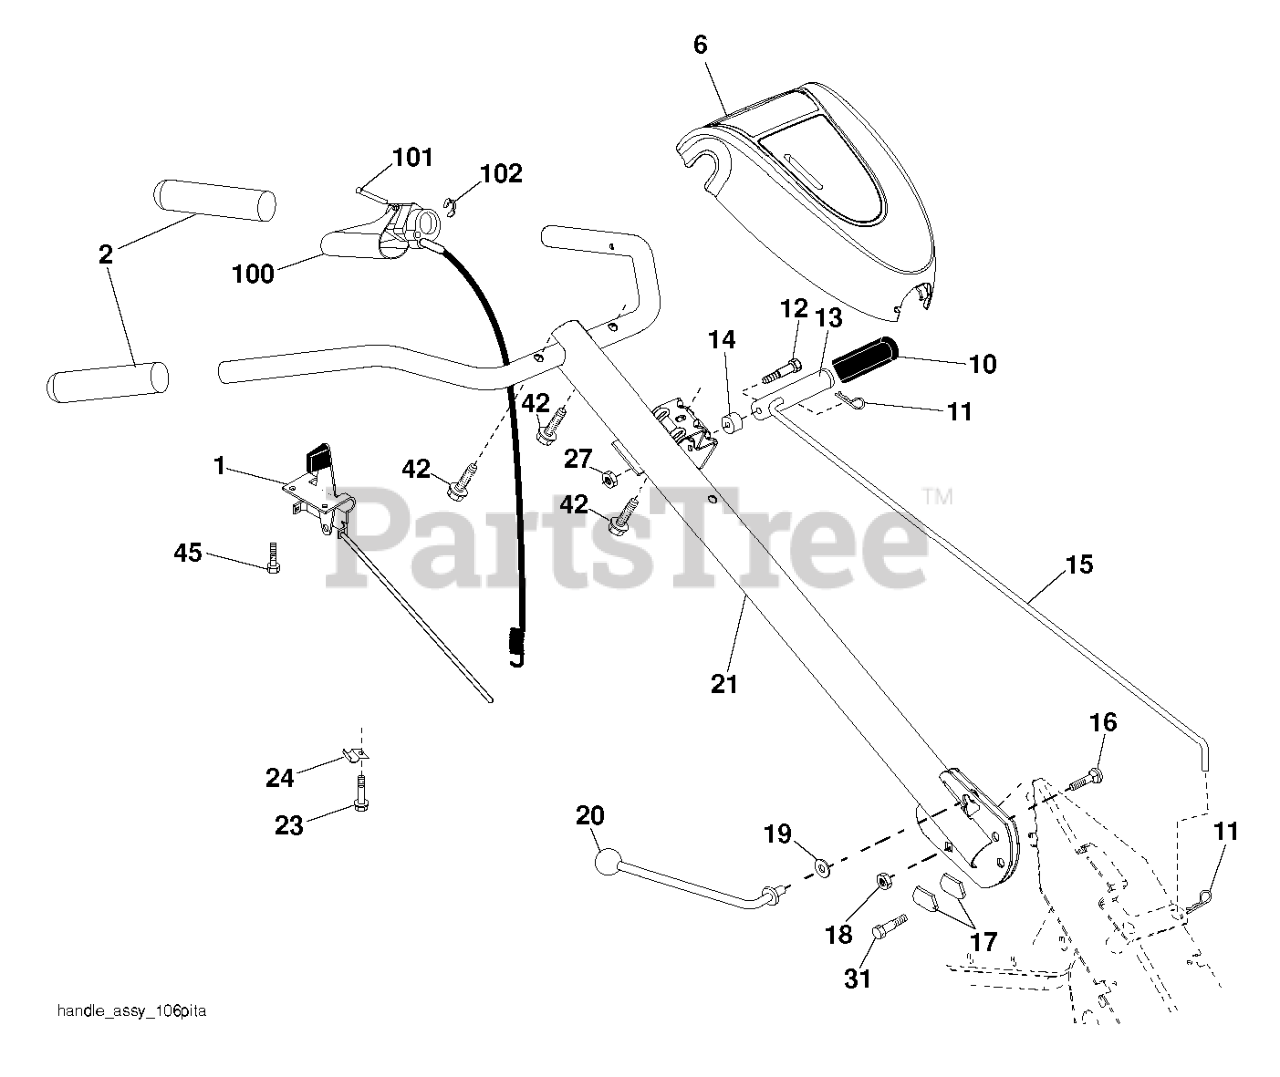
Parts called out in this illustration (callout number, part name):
1	THROTTLE.CONTROL.RT.INTEK.50
2	GRIP.1X5.06
6	CONSOLE.GREY.DRT.W.S.DRT900E
10	GRIP T
11	RETAINER M
12	SHOULDER BOLT ST
13	HANDLE
14	GROMMET.RUBBER.CRT.TILLER
15	ROD SHIFT RT UNIVERSAL
16	BOLT D
17	LOCK.HANDLE.CRT
19	WASHER CRT
20	LEVER.LOCK.CRT
21	HANDLE.ASM.HUSQ/P.PRO.GREY
23	TAPPING SCREW
24	CLIP.PLATED
27	NUT T
31	BOLT.PIVOT
42	SCREW.#10 X 0.750.BOS
45	SCREW.#10 X 0.500
100	CONTROL.ASSEMBLY.TINE.TILLER
101	PIN, PIVOT
102	RETAINING.RING.#5103-25
